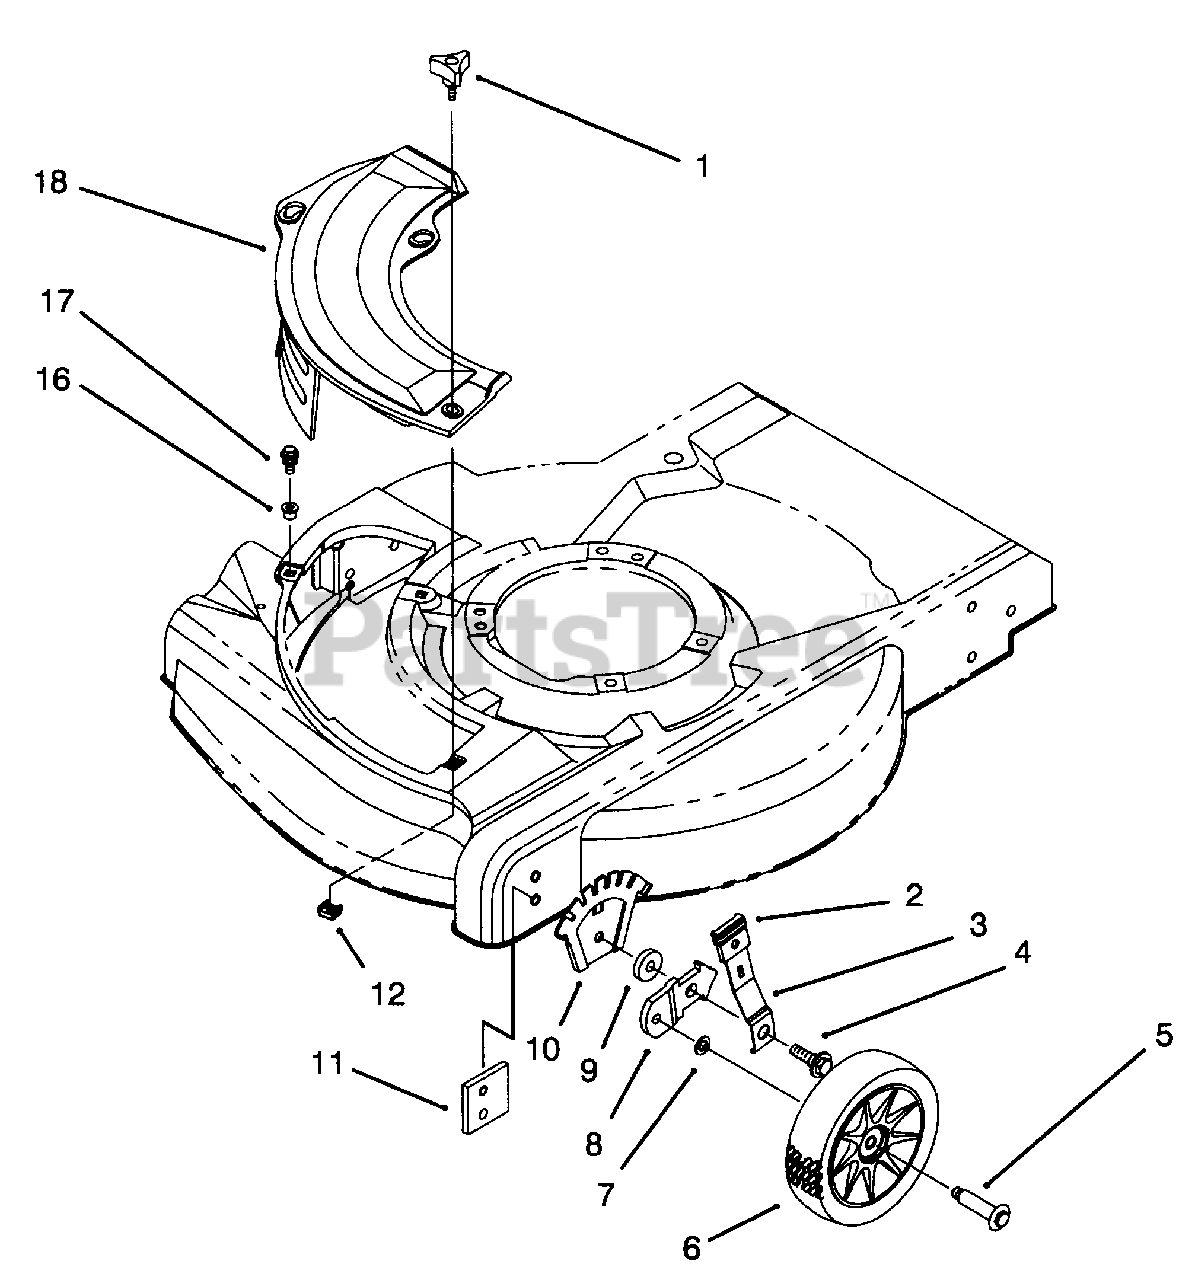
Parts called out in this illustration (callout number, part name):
1	Knob-Cover Plate
2	Knob-Height Adjust
3	Spring Arm-Front
4	Bolt-Shoulder
5	Bolt-Shoulder
6	Wheel & Tire Ass'y 6"
8	Bracket-Wheel Height Adj.
10	Plate-Height Adjust.
11	Plate-Baffle
12	Nut-Cage
16	Grommet-Plastic
17	Screw-Sems Thr'd Form
18	Plate-Mulch 21"
